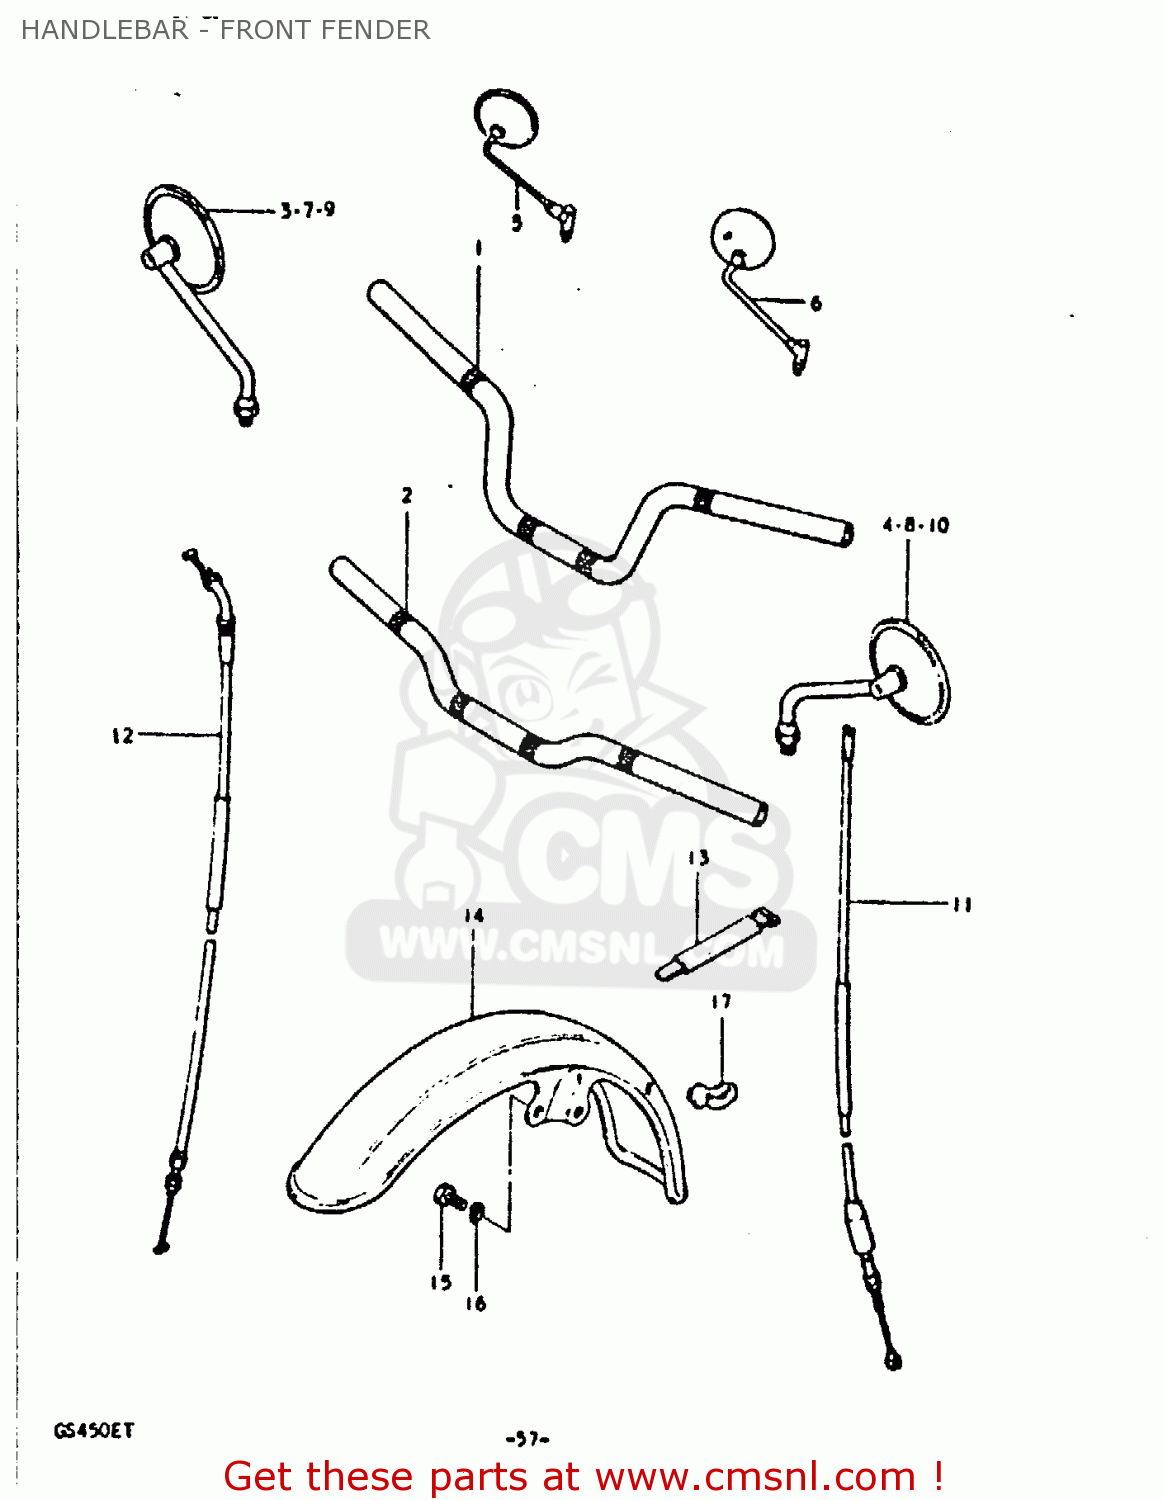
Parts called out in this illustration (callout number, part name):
1	HANDLEBAR
2	HANDLEBAR
3	MIRROR ASSEMBLY,RIGHT
4	MIRROR ASSEMBLY,LEFT
5	MIRROR ASSY,RR VIEW
11	CABLE ASSY,CLUTCH
12	CABLE ASSEMBLY,THROTTLE
13	CLAMP
14	FENDER,FR
15	BOLT
16	LOCK WASHER
17	GUIDE,CABLE
